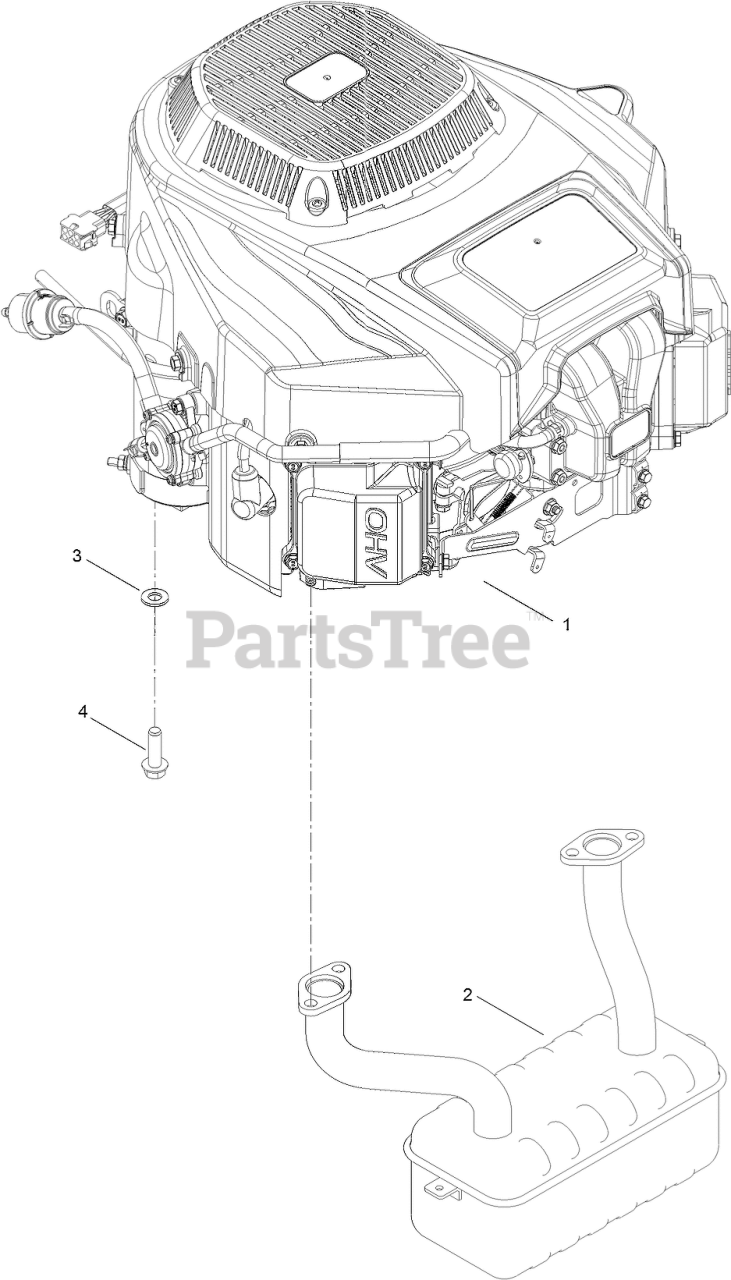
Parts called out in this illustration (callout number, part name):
1	ENGINE-2P77F
2	MUFFLER
3	WASHER-FLAT
4	SCREW-THD
